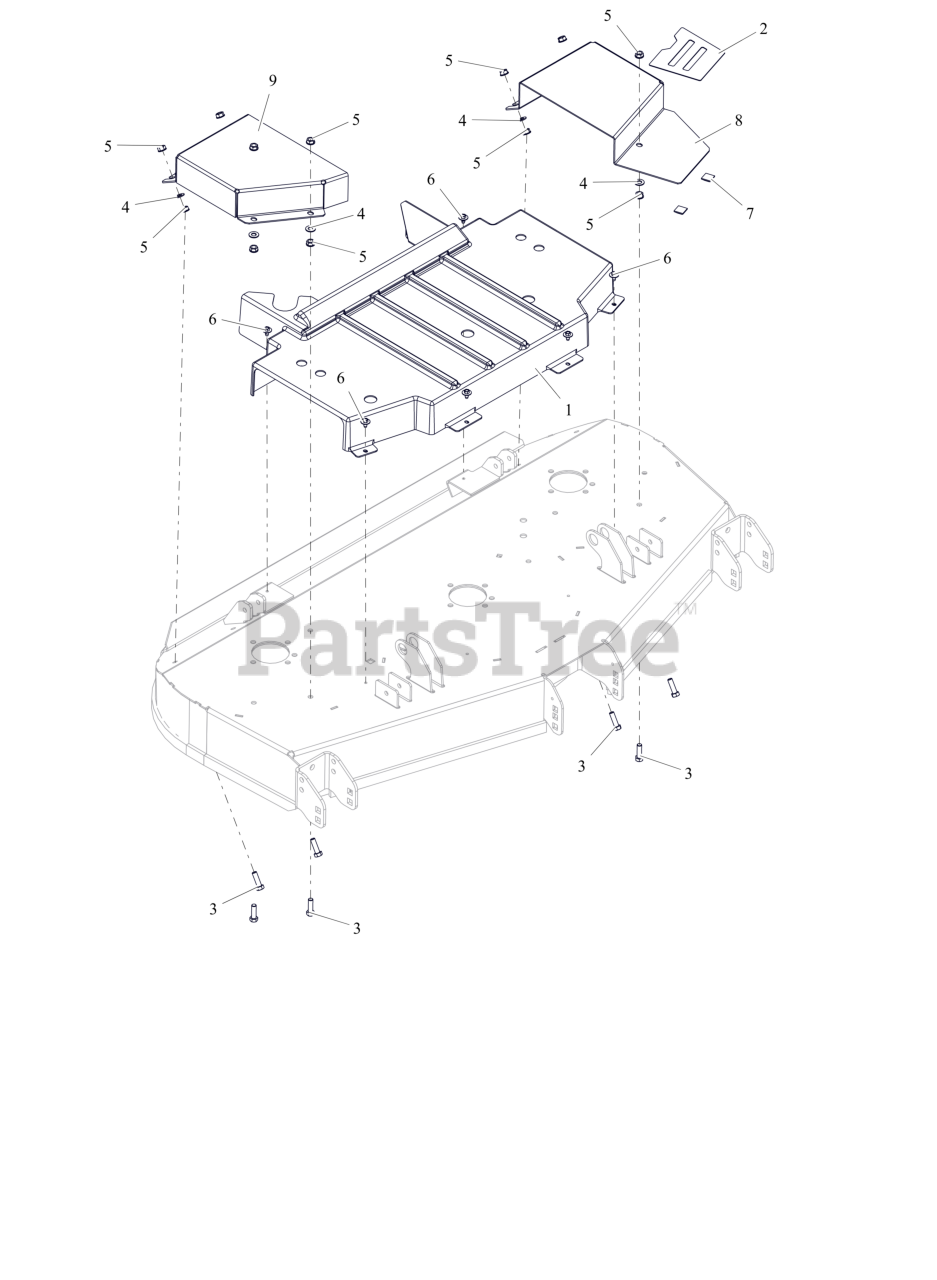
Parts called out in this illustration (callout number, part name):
1	GUARD,CENTER,DECK SPINDLE CE
2	GRIP TAPE 52-60 BELT COVER
3	BLT, HEX .38-16X1.25 G5 ZCC
4	WSHR,FLT .406X.812X.065 ZCC
5	NUT, SPNLK-FLG .38-16 G5 ZCC
6	SCR, TAP .25-20X.50 LG HWH ZCC
8	GUARD, BELT 52" LEFT
9	GUARD, BELT 52" RIGHT CE (ORANGE)
